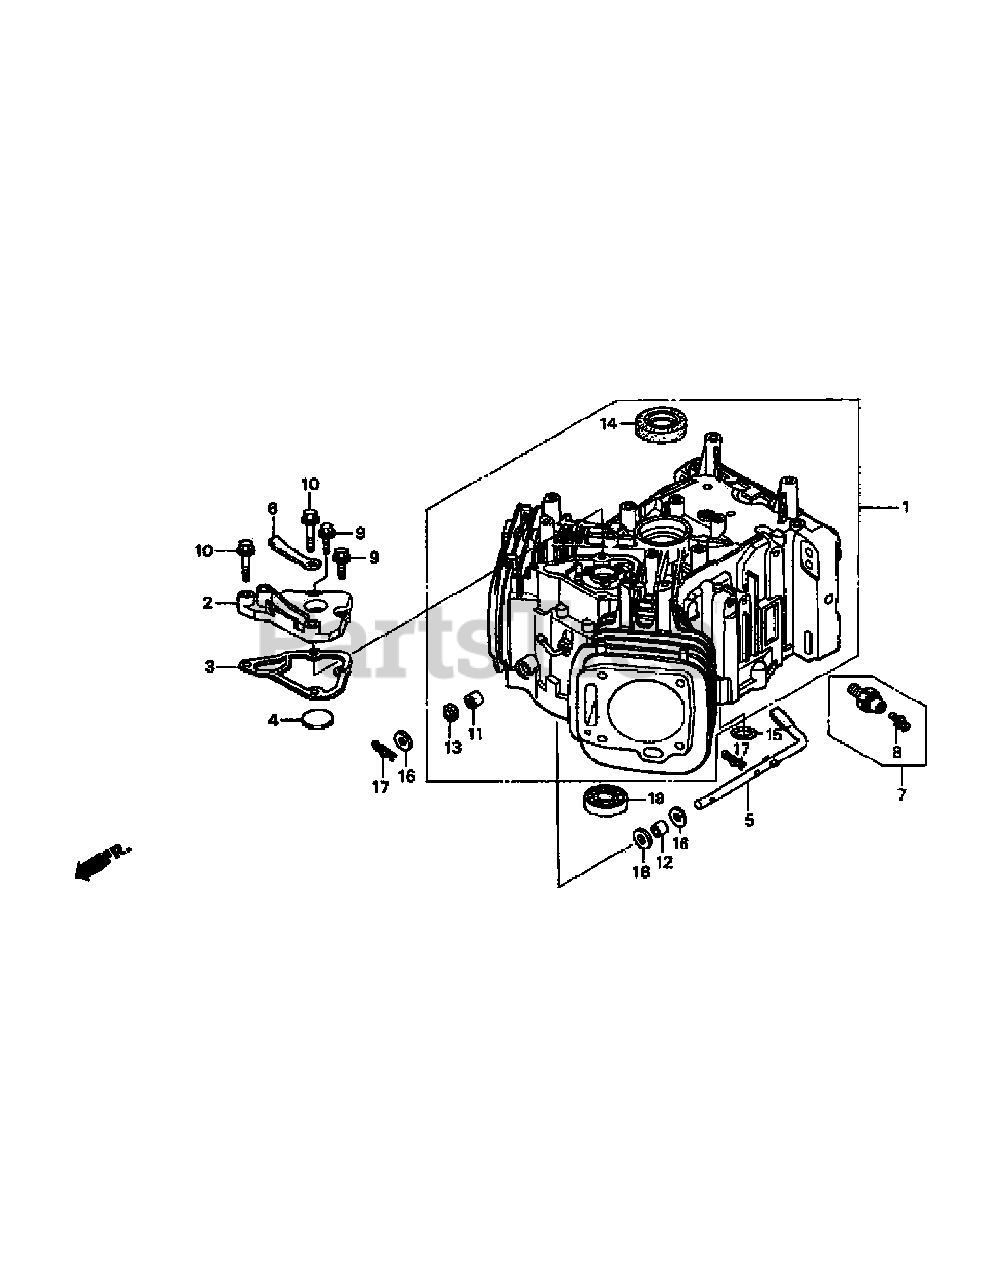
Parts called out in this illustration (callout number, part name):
1	Cylinder Assy.
2	Breather Cover
3	Breather Cover Gasket
4	Breather Valve
5	Governor Arm Shaft
6	Wire Clamp
7	Oil Pressure Switch
8	Screw Washer (4x8)
9	Flange Bolt (6x16)
10	Flange Bolt (6x32)
11	Needle Bearing (8x12.7x11.1)
12	Needle Bearing (8x12x10)
13	Oil Seal (8x14x5)
14	Oil Seal (38x58x9)
15	O-Ring (13x3.0)
16	Plain Washer (8mm)
17	Lock Pin (8mm)
18	Radial Ball Bearing
